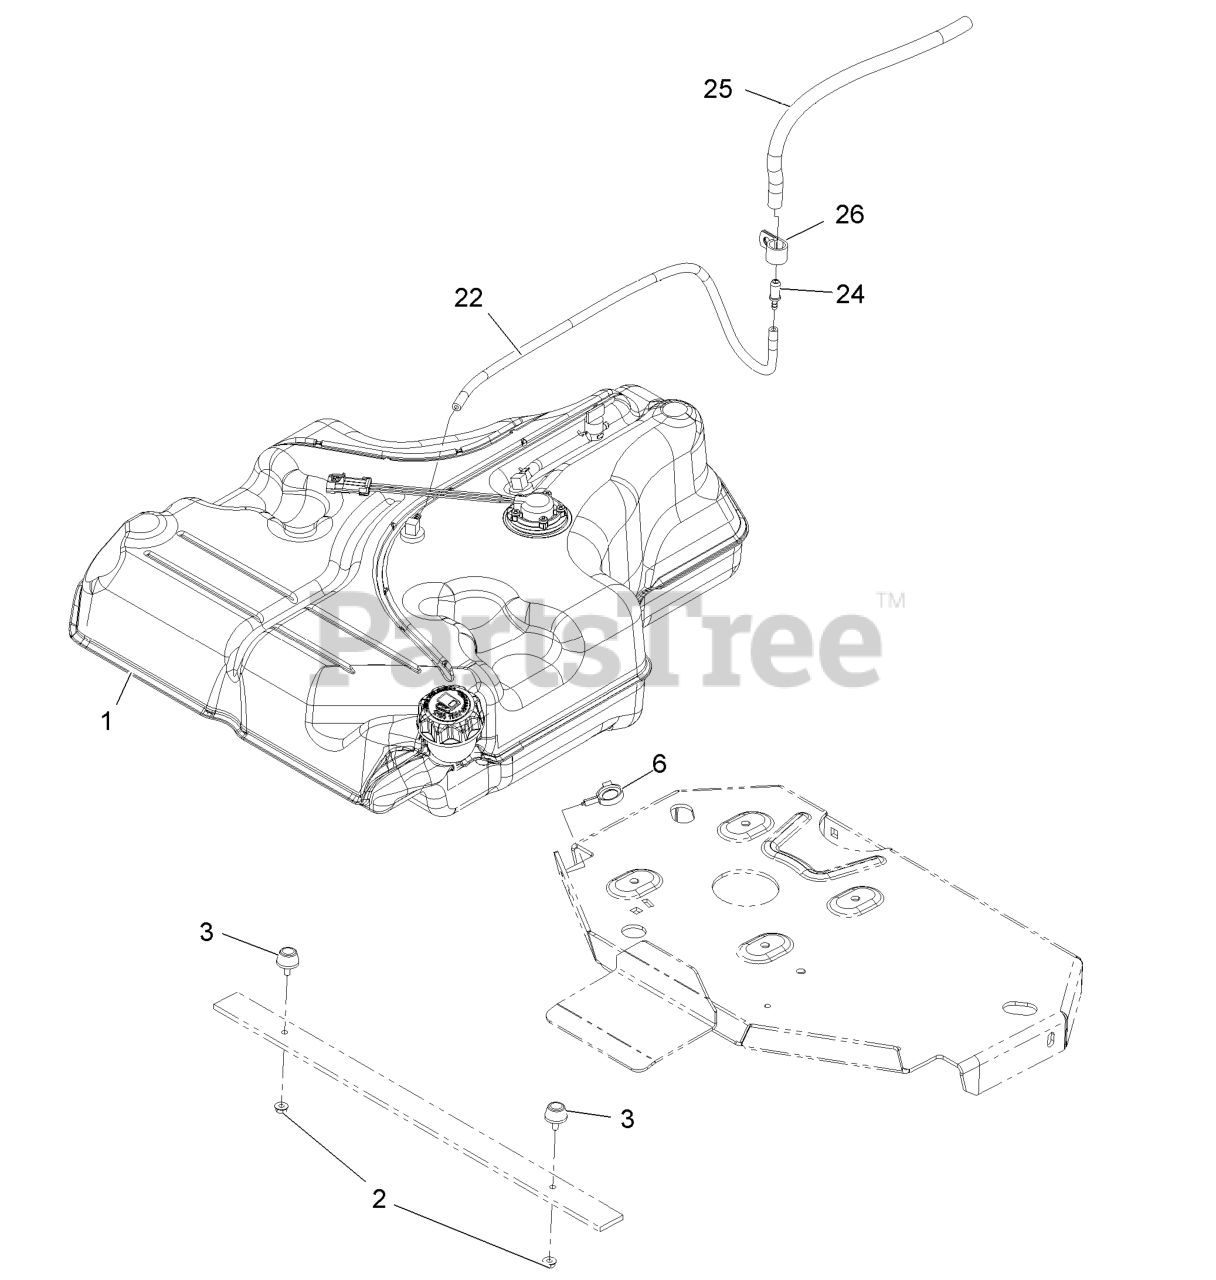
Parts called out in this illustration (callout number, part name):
3	BUMPER-RUBBER
6	CLAMP-HOSE
22	HOSE-FUEL
24	FITTING-STRAIGHT
25	HOSE-FUEL
26	CLIP-LOOM
